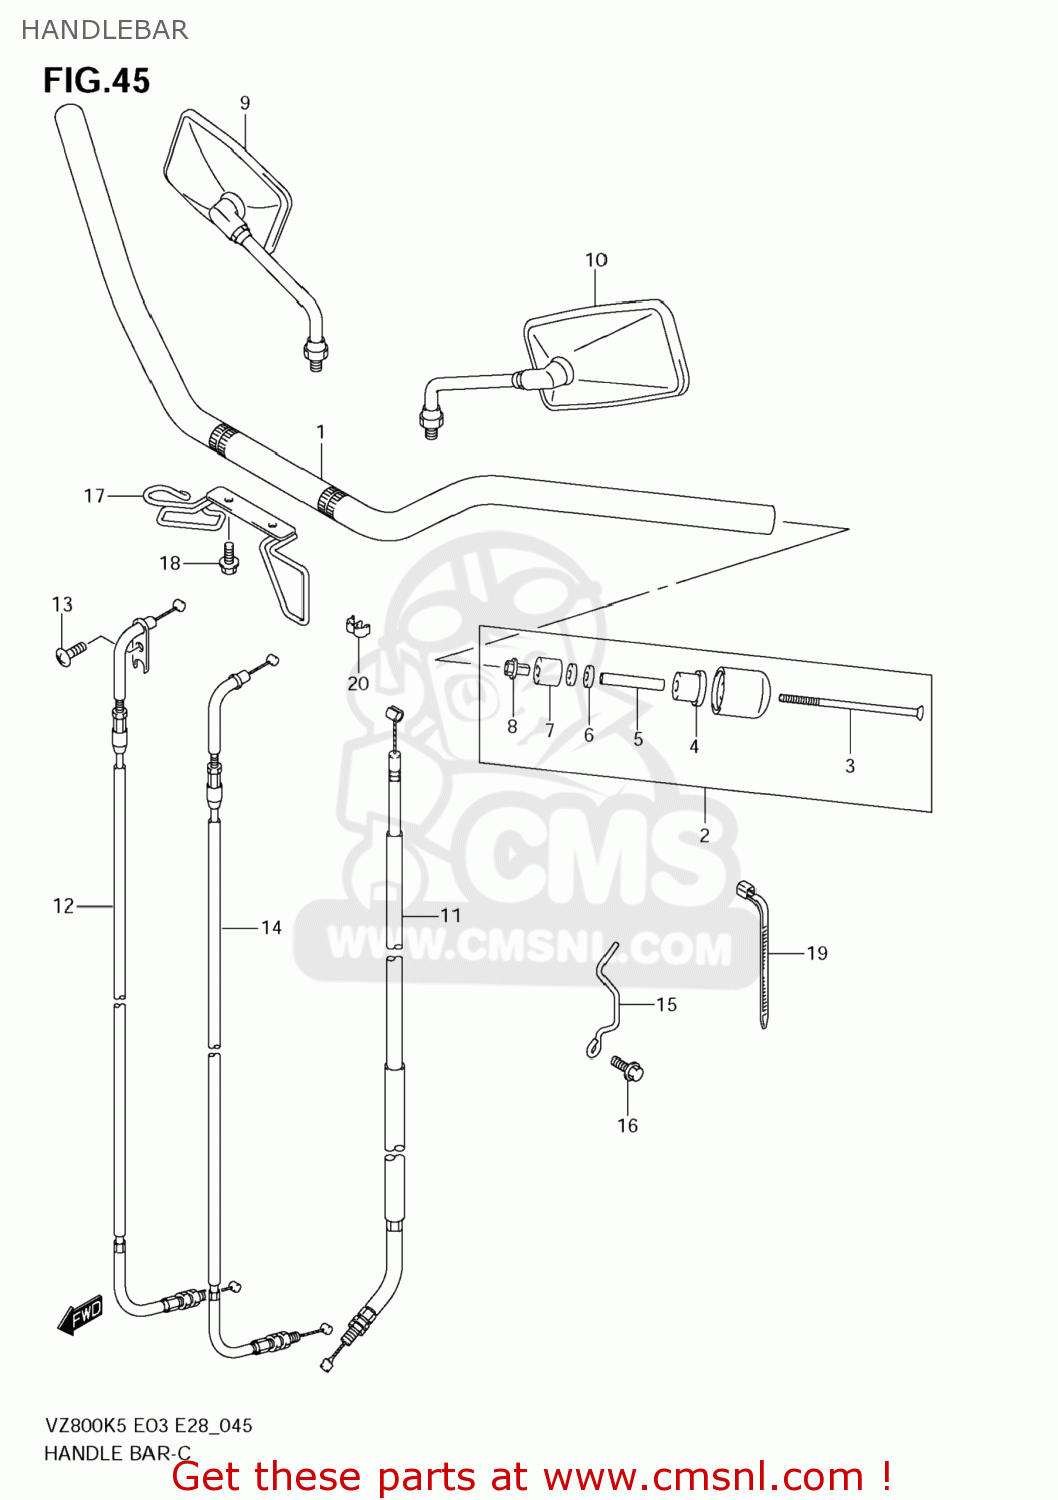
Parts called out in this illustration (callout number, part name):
1	HANDLEBAR
2	BALANCER SET,HANDLEBAR
3	SCREW(6X127)
4	EXPANDER,HANDLE BALANCER NO.2
5	SPACER,EXPANDER
6	WASHER(6.5X16X4)
7	EXPANDER,HANDLE BALANCER
8	NUT,HANDLE BALANCER
9	MIRROR ASSY,RR VIEW,R
10	MIRROR ASSY,RR VIEW,L
11	CABLE ASSY,CLUTCH
12	CABLE ASSY,THROTTLE NO.1
13	SCREW
14	CABLE ASSY,THROTTLE NO.2
15	GUIDE,THROTTLE CABLE
16	BOLT
17	GUIDE,CABLE
18	BOLT
19	CLAMP(L:190)
20	CLIP
